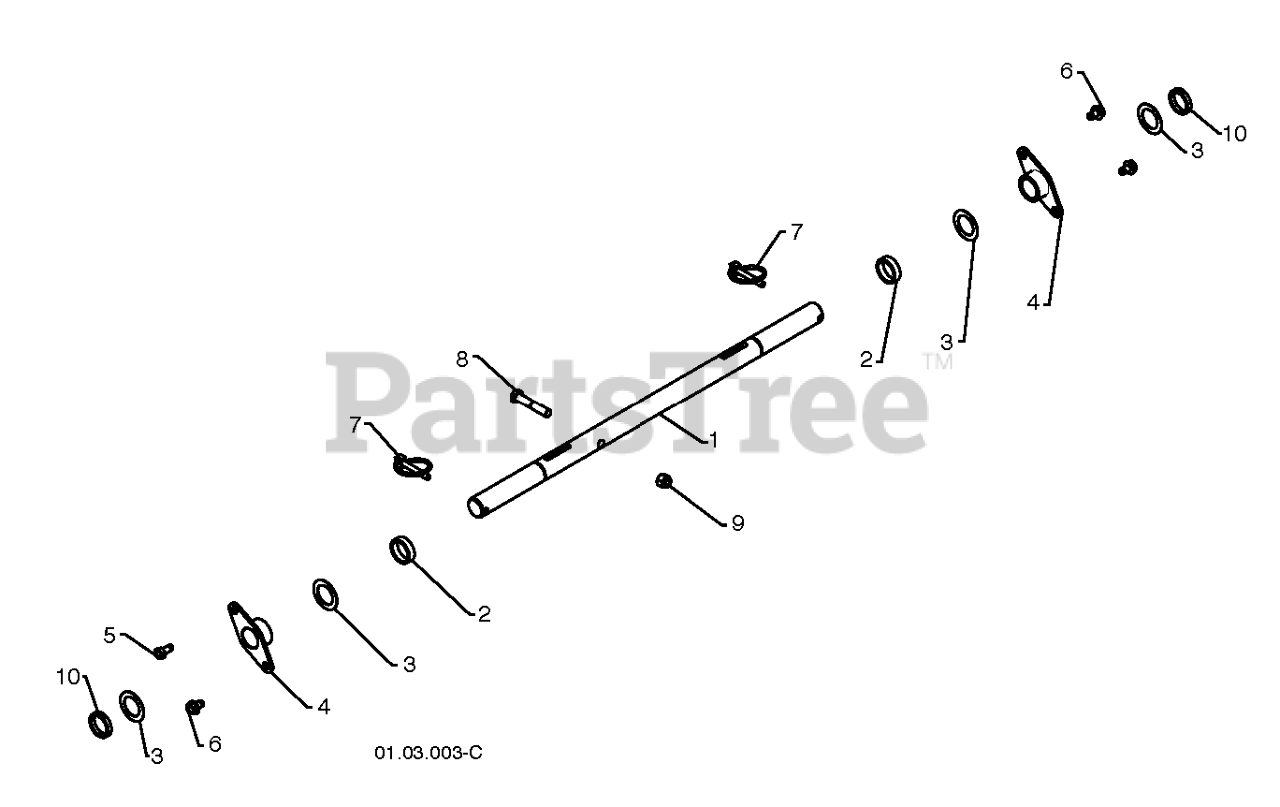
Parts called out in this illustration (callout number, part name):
1	SHAFT.AXLE.POWER.STEERING.HYD
2	SPACER.AXLE.RH
3	WASHER 1.00
4	BEARING, AXLE
6	Screw 5/16-18 x 1/2 Hex, Self Tapping 5/16-18 x 1/2
7	PIN KLIK, 1/4
8	CAP.SCREW.HEX.HD.3/8-16
9	NUT
10	SPACER.AXLE.END.TRACK
